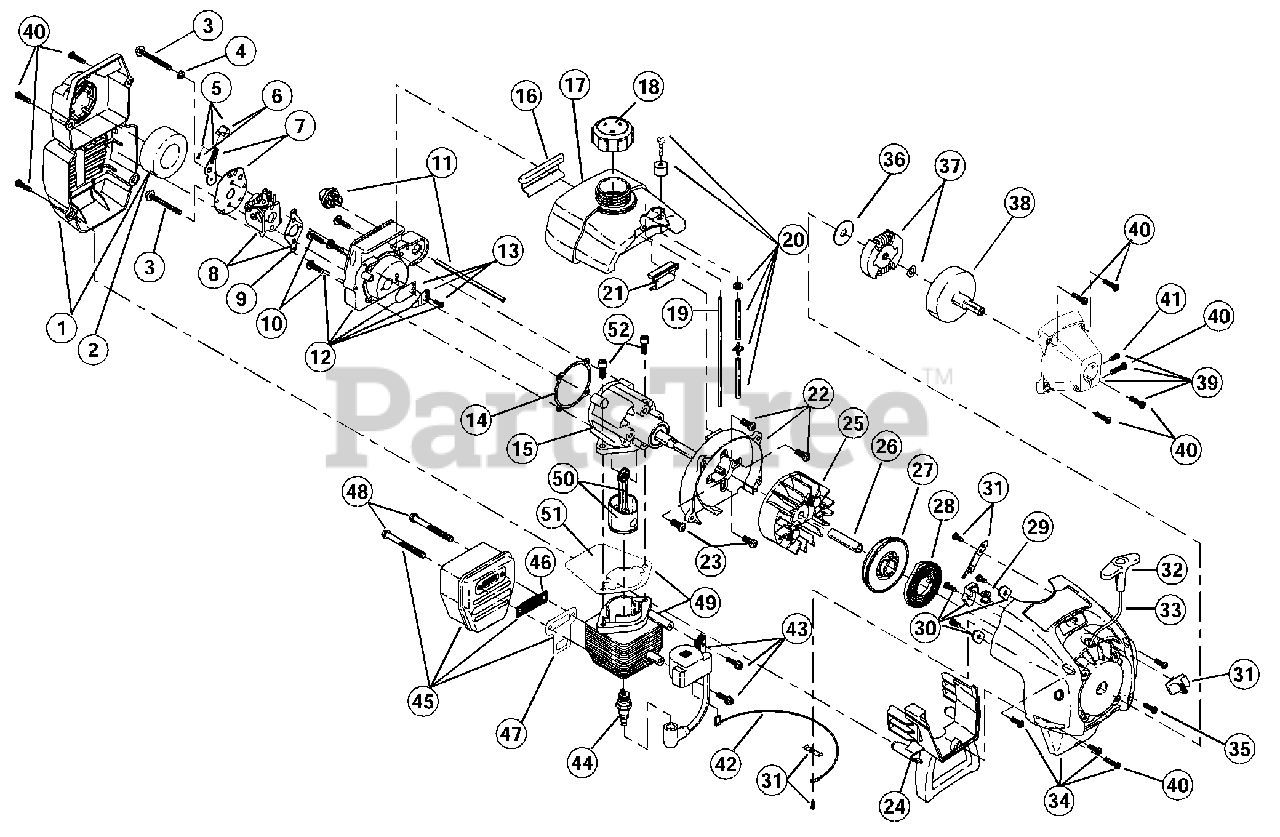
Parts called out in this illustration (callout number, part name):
1	Air Cleaner/Muffler Cover Assembly
2	Air Cleaner Filter
3	Carburetor Mounting Screw Assembly
4	Wavey Washer
5	Choke Lever Assembly
6	Choke Knob and Screw
7	Choke Lever and Plate
8	Carburetor Assembly
9	Carburetor Gasket
10	Carb Mount Screw
11	Primer and Hose Assembly
12	Carb Mount Assembly
13	Reed Assembly
14	Carburetor Mount Gasket
15	Crank Case Service Assembly
16	Rear Mounting Pad
17	Fuel Tank Assembly
18	Fuel Cap Assembly
19	Fuel Return Line
20	Fuel Line Assembly
21	Front Mounting Pad
22	Shroud Assembly
23	Shroud Screw
24	Shroud Extension & Stand
25	Flywheel Assembly
27	Recoil Pulley Assembly
28	Recoil Spring
29	Rope Guide
30	Pulley Retainer Assembly
31	Switch Assembly
32	Pull Handle
34	Starter Housing Assembly
35	Housing Screw
36	Clutch Washer
37	Clutch Rotor Assembly
38	Clutch Drum Assembly
39	Clutch Cover Assembly
40	Cover Screw
41	Anti-Rotation Screw
42	Wire Lead
43	Module Assembly
44	Spark Plug
45	Muffler Assembly
46	Spark Arrestor Screen
47	Exhaust Gasket
48	Muffler Mounting Bolt Assembly
49	Cylinder Assembly
50	Piston and Rod Assembly
51	Cylinder Gasket
52	Cylinder Bolt
